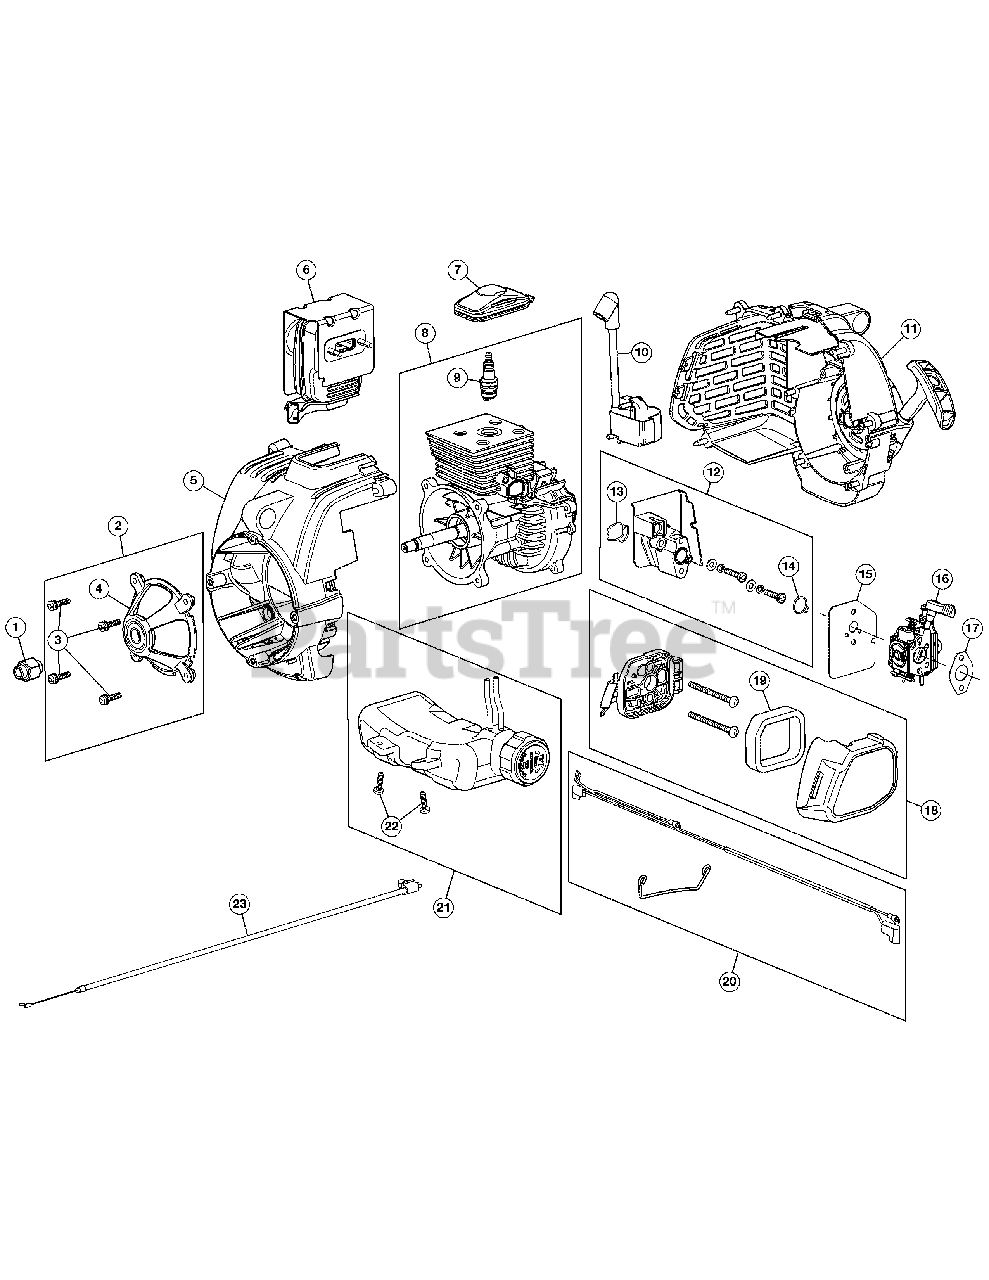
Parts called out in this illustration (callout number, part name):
2	Bearing Holder Assembly (Incl. 3 and 4)
4	Bearing Holder
5	Front Engine Cover Assembly
6	Muffler Assembly
7	Spark Plug Cover
8	Short Block Assembly (Incl. 9)
9	Spark Plug
10	Module Assembly
11	Rear Engine Cover Assembly
12	Insulator Assembly (Incl. 13 and 14)
13	Insulator O-Ring
14	Carburetor O-Ring
16	Carburetor
17	Carburetor Gasket
18	Air Cleaner Assembly
19	Air Cleaner Filter
20	Lead Wire Assembly
21	Fuel Tank Assembly (Incl. 22)
22	Screw (x2)
23	Throttle Cable
